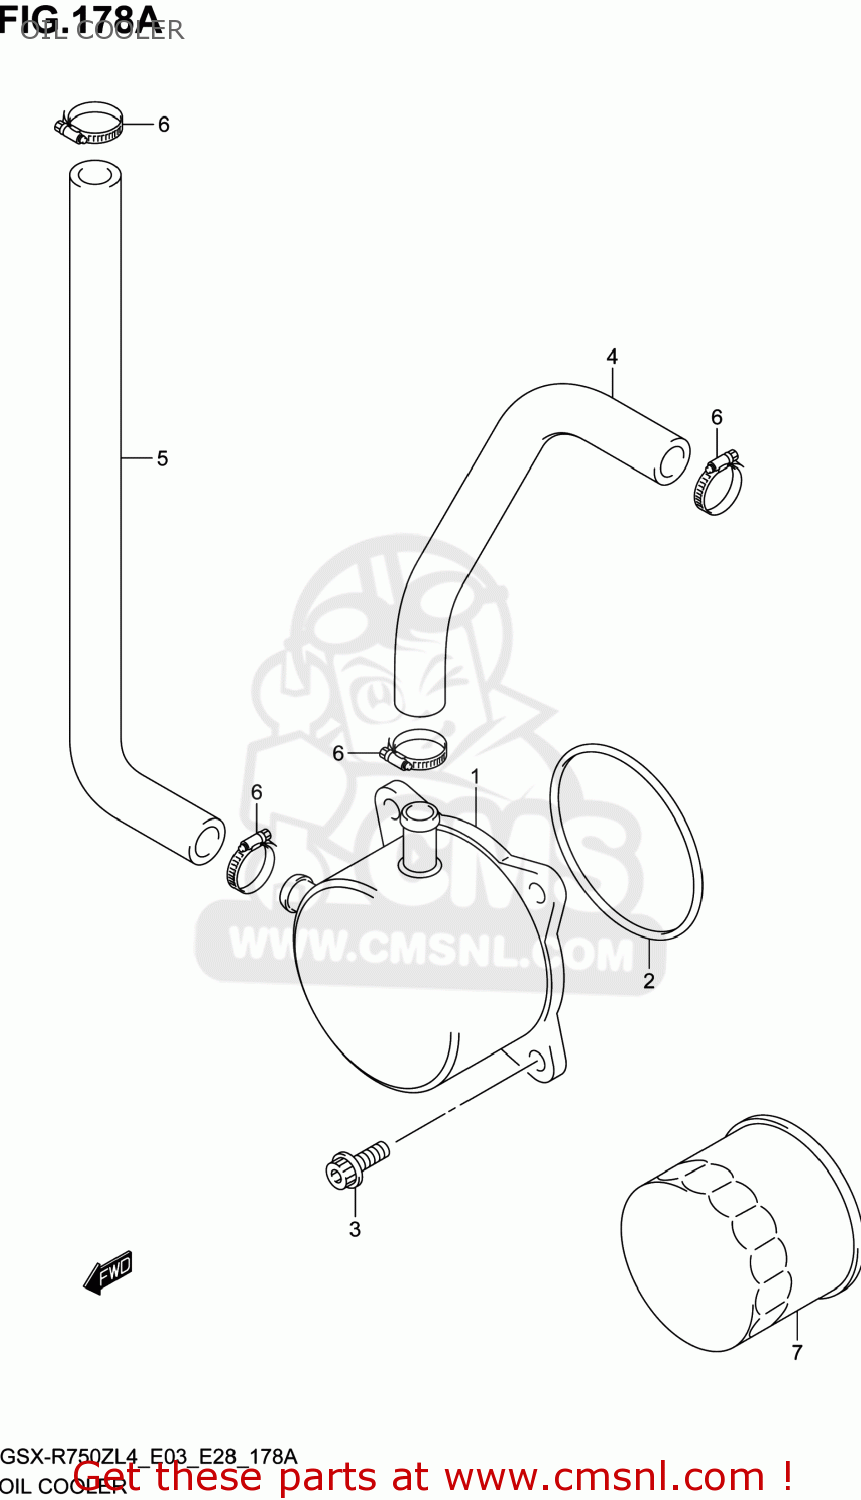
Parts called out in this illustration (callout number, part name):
1	COOLER ASSY,OIL
2	O RING(D:3.1,ID:63.9)
3	BOLT(6X16)
4	HOSE,OIL COOLER WATER INLET
5	HOSE,OIL COOLER WATER OUTLET
6	CLAMP
7	FILTER ASSY,ENGINE OIL
